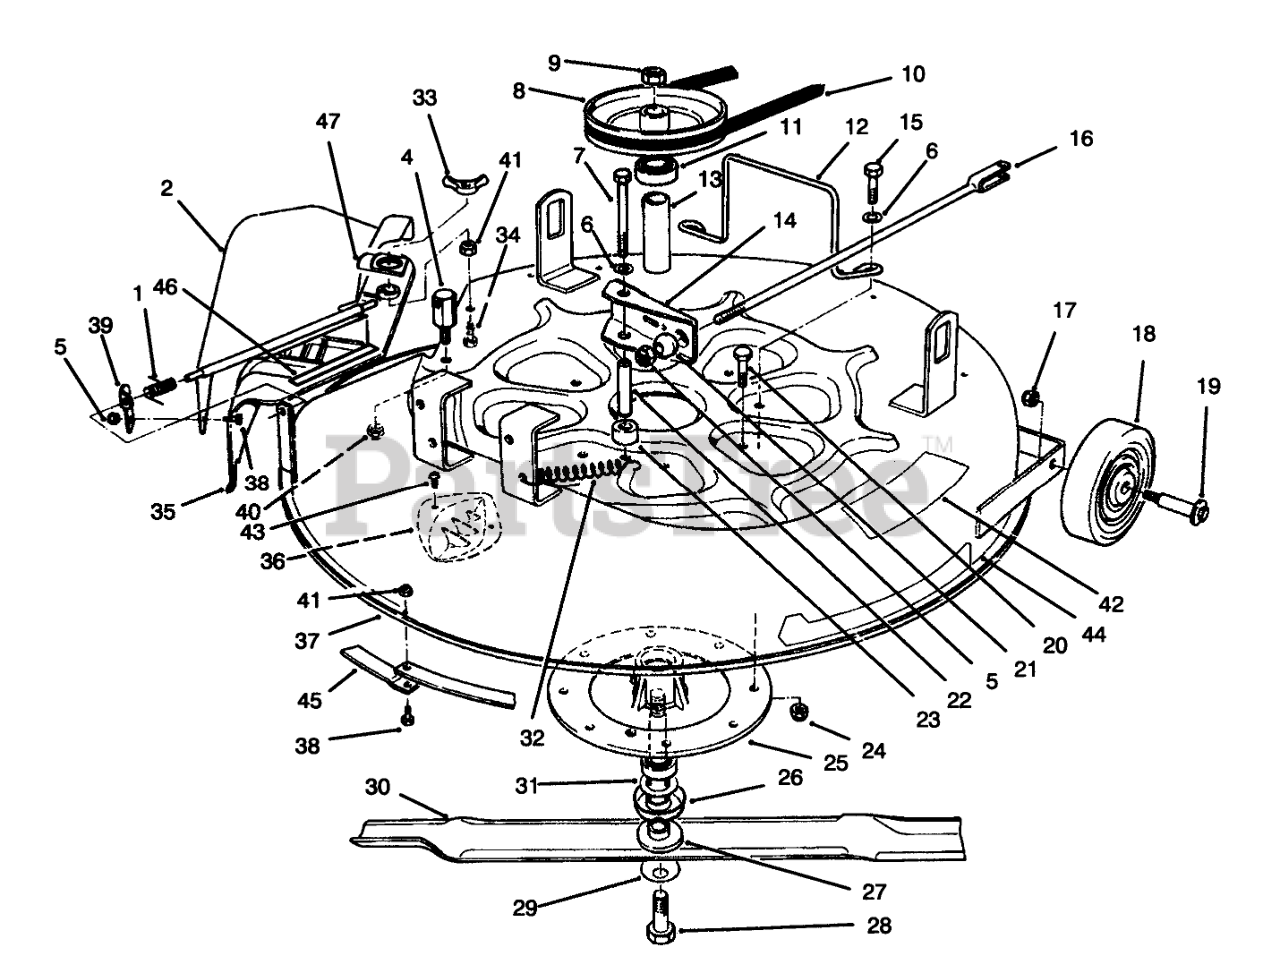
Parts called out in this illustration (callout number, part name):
1	SPRING
2	Deflector
4	POST-PIVOT
5	NUT-HEX
6	WASHER-PLAIN
7	SCREW-HH
8	PULLEY-DECK
9	NUT-HEX
10	V-Belt
11	BEARING-BALL
12	GUIDE-DECK BELT
13	SPACER-BEARING
14	Assy.-Brake, Deck
15	SCREW-HH
16	DECK BRAKE ROD WA
17	NUT-LOCK, NI
18	WHEEL-DECK
19	BOLT-WHEEL
20	SCREW-HH
21	BALL-SWIVEL, STOP
22	POST-BRAKE MTG
23	SPACER-DECK BRAKE
24	NUT-LOCK, NI
25	CASTING-SPINDLE
26	SHIELD-BEARING
27	SHAFT-SPINDLE
28	SCREW-HH
29	WASHER-BELLEVILLE
30	Blade
31	SPACER
32	SPRING-EXTENSION
33	Nut-Wing
34	SCREW-HHF
35	COVER- 25" (W/KICKER)
36	KICKER
37	Deck (Incl. Ref. #42)
38	SCREW-HH
39	BRACKET-DEFLECTOR
40	NUT-LOCK, NI
41	NUT-LOCK, NI
42	DECAL - DANGER
43	SCREW-PPH
44	DECAL - RECYCLER 25"
45	25" RECYCLER RING (BLACK)
46	DECAL-DANGER, DEFLECTOR
